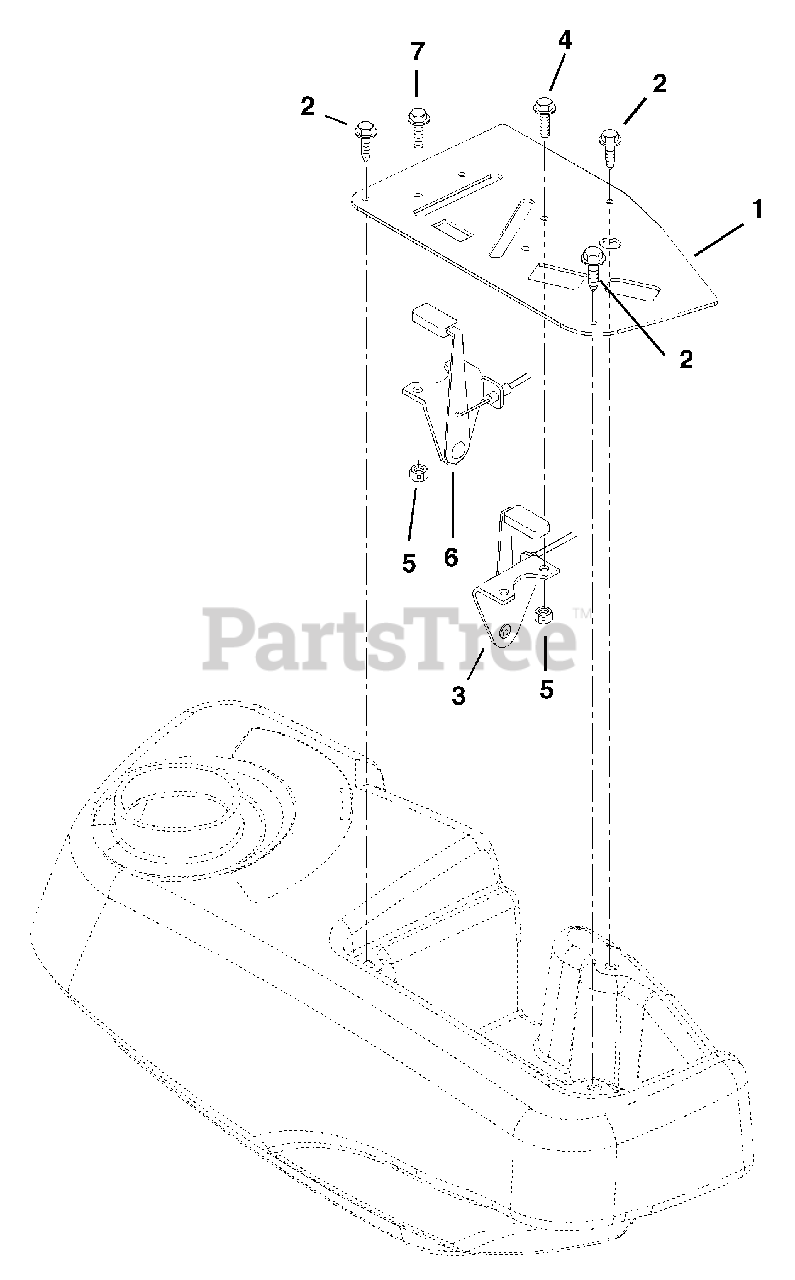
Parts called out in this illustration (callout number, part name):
1	Panel-Control
2	Screw-Machine 10 - 24 x .50 Hex Washer Head
3	Throttle Control
4	Screw-Machine 10 - 24 x .50 Hex Washer Head
5	Nut-Locking-Nylon 10 - 24 With Insert
6	Choke Control
6	Choke-Control
7	Screw-Machine 10 - 24 x .50 Hex Washer Head
